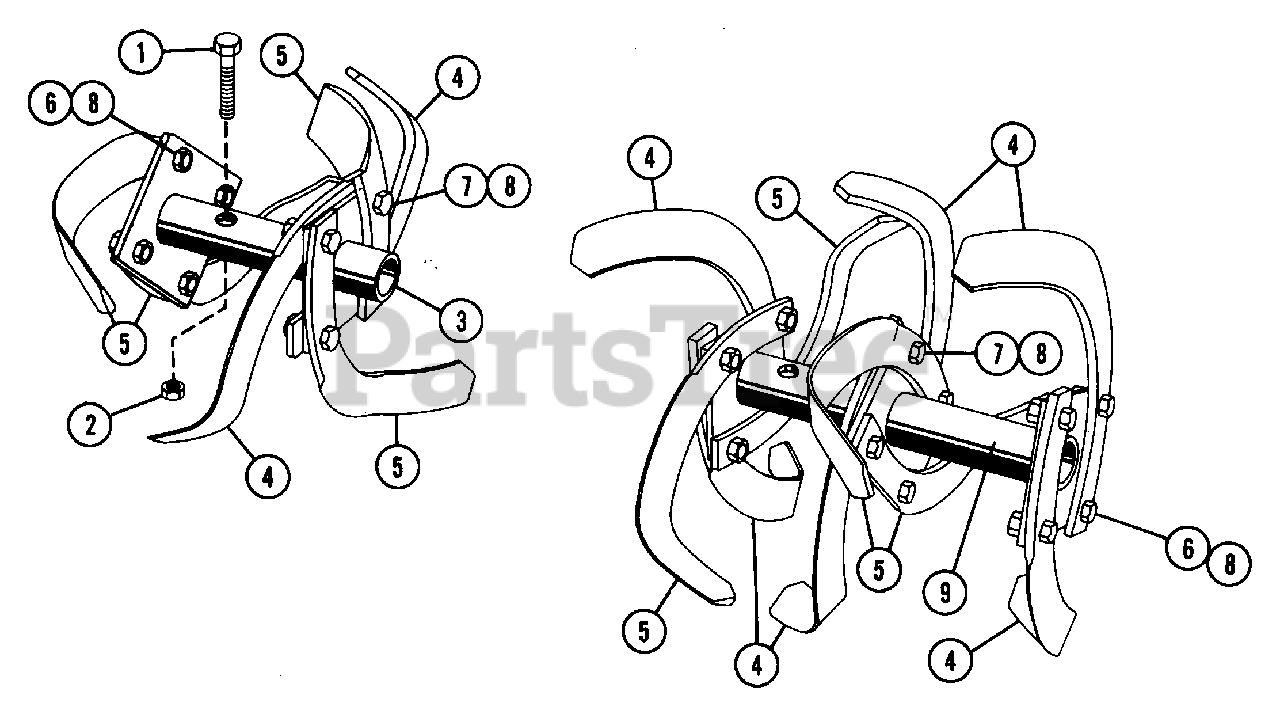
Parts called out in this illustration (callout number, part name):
1	BLT-HEX .38-16X1.75 PL GR2
2	NUT-LK-CTR .375-16 GR A PL
3	SHORT TINE TUBE WELDMENT
4	TINE L.H.
5	TINE R.H.
6	BLT-HEX .44-14X1.00 GR5
7	BLT-HEX .44-14X1.50 GR5
8	NUT-LK-TOP .437-14 GR C PL
9	LONG TINE TUBE WELDMENT
